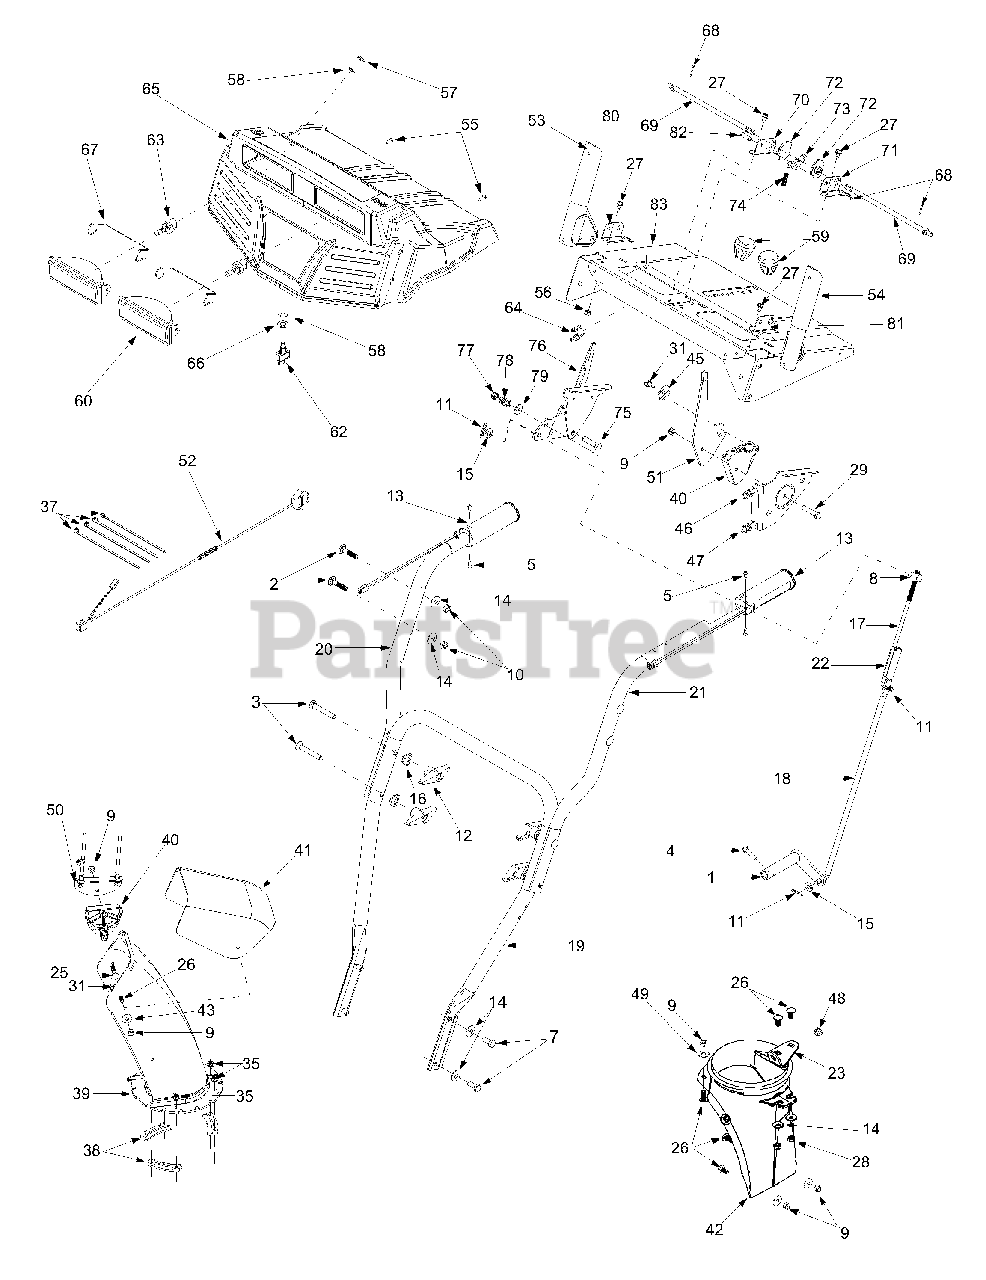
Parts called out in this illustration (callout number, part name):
2	Carriage Bolt 5/16-18 x 1.75"
3	Carriage Bolt 5/16-18 x 2.25"
4	TT Screw 1/4-20 x 1"
5	C-Sunk Screw #10-16x 0.625"
7	Hex Screw 5/16-18 x .75"
8	Ferrule
9	Hex Lock Nut 5/16-18
10	Hex Nut 5/16-18
11	Cotter Pin
12	Handle Knob
13	Heated Grip
14	Belleville Washer
15	Flat Washer
16	Saddle Washer
17	Shift Rod: Upper
18	Shift Rod: Lower
25	Carriage Bolt: 5/16-18 x 1.5"
26	Carriage Bolt: 5.16-18 x .750"
27	TT Screw: 1/4-20 x 0.5"
28	Hex Nut 5/16-18
29	Hex Screw: 5/16-18 x 1.5"
31	Hex Screw AB:1/4-14 x 0.625"
35	Hex Flange Lock Nut
37	Cable Tie
38	Chute Flange Keeper
39	Lower Chute
40	Cable Guide: Chute Tilt
41	Upper Chute
43	5/16 Washer
45	Special Washer
46	Control Cable
47	Control Cable
48	Plastic Bushing
49	5/16 Washer
52	Harness Assembly: Upper
53	Handle Assembly RH
54	Handle Assembly LH
55	Special Hex Screw
56	Hex Sems Nut: 1/4-20
58	Lock Ring: Toggle Switch
59	Shift Knob
60	Lamp Housing
62	Toggle Switch: Single Switch
63	Halogen Lamp: 27W, 12V
64	Mounting Clamp
65	Handle Panel
66	Flat Washer
67	Headlight Retainer
68	Cotter Pin: 3/32 x .75
72	Cam Handle Lock
73	Handle Lock Pawl
74	Compression Spring: .36 x 1.0
75	Hex Cap Screw: 3/8-24 x 1.5
78	Comp. Spring: .39 x .6 x .88
79	Bell Washer
82	Clevis Pin
